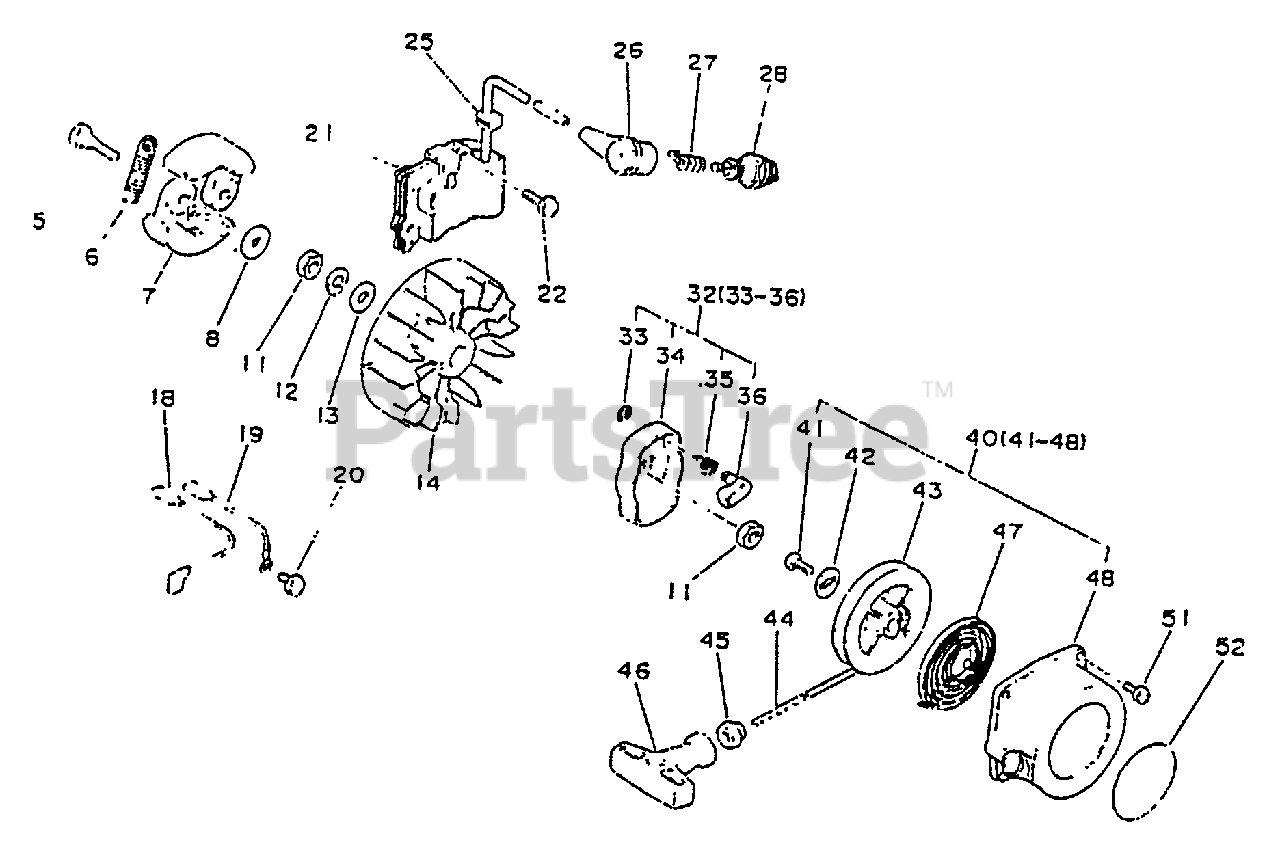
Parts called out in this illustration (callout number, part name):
5	BOLT, CLUTCH
6	SPRING, CLUTCH
7	SHOE, CLUTCH
8	WASHER - 6
12	LOCKWASHER - 8
13	WASHER - 8
14	FLYWHEEL
18	LEAD
19	LEAD - GROUND
20	SCREW - 5X10
21	COIL, IGNITION
22	SCREW - 5X20
26	CAP, SPARK PLUG
27	TERMINAL, SPARK PLUG CAP
28	SPARK PLUG -- BPM-7A
32	STARTER PAWL ASSY
33	RING, RETAINING - 4
34	CATCHER, PAWL
35	SPRING, RETURN
36	PAWL, STARTER
40	STARTER ASSY
42	WASHER
43	REEL, ROPE
44	ROPE, STARTER - 3.5X850
45	GUIDE, ROPE
46	GRIP, STARTER
47	SPRING, REWIND
48	CASE, STARTER
51	SCREW - 4X14
52	LABEL - ECHO
